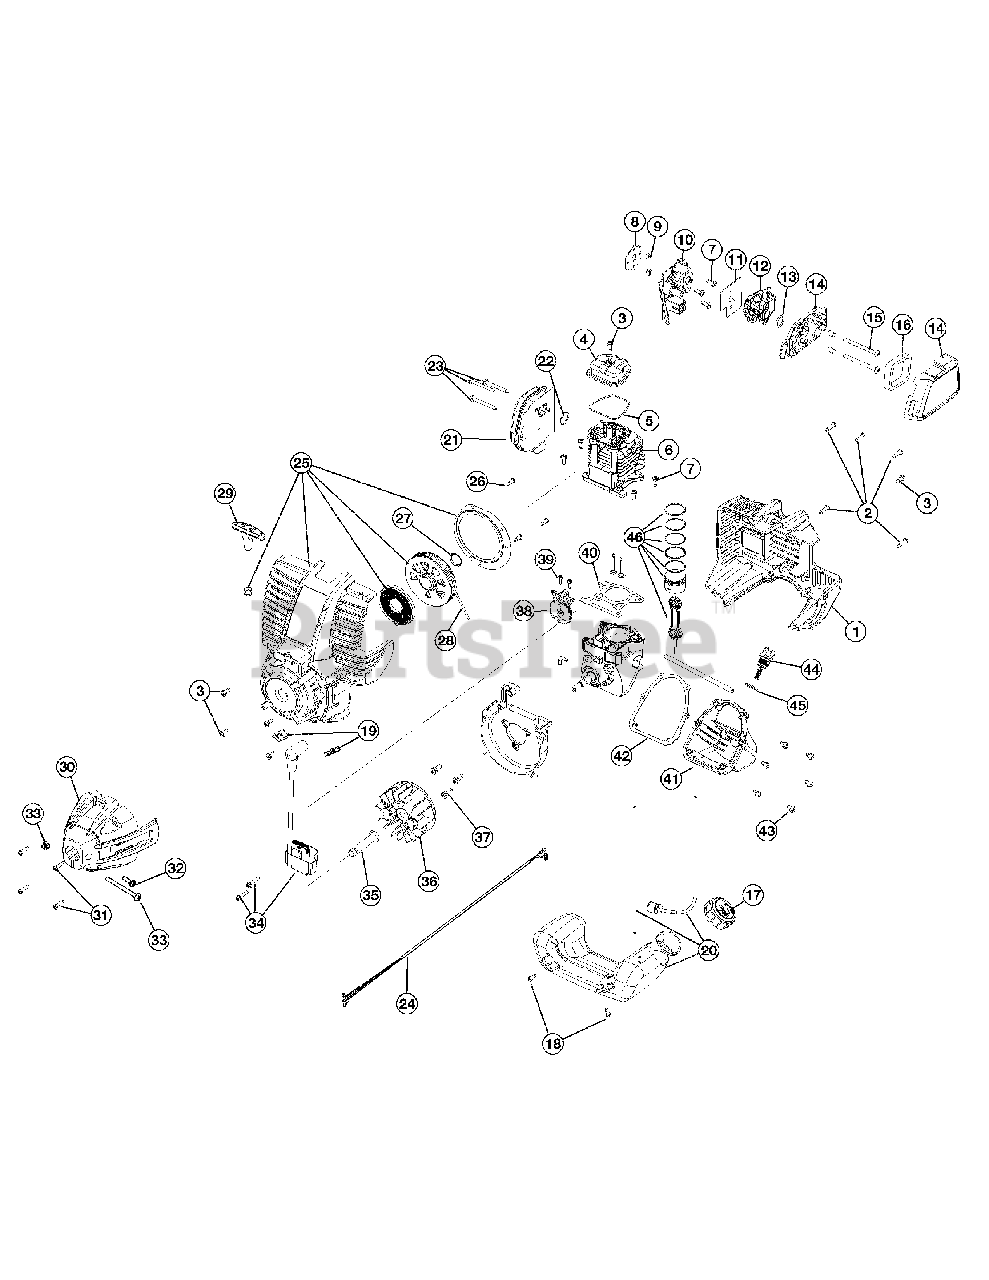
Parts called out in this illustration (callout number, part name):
1	Engine Cover
4	Valve Cover
5	Valve Cover Gasket
6	Cylinder Assembly
7	Cylinder Screw
8	Insulator Gasket
9	Nut
10	Insulator
11	Carburetor Gasket
12	Carburetor w/Primer
13	Carburetor O-Ring
14	Air Filter Cover Assembly
15	Air Filter Mounting Screw
16	Air Filter
20	Fuel Tank Assembly
21	Muffler Assembly
22	Muffler Gasket
23	Muffler Moutning Screw
25	Starter Housing Assembly
26	Plate Screw
29	Pull Handle
30	Clutch Cover Assembly
31	Cover Screw
32	Anti-Rotation Screw
33	Clamping Screw Assembly
34	Ignition Module Assembly
35	Square Nut Drive
37	Shroud Screw
38	Cam Bracket Assembly
39	Cam Bracket Screw
40	Cylinder Gasket
41	Oil Pan
42	Oil Pan Gasket
43	Oil Pan Screw
44	Dipstick Assembly
46	Piston Assembly
